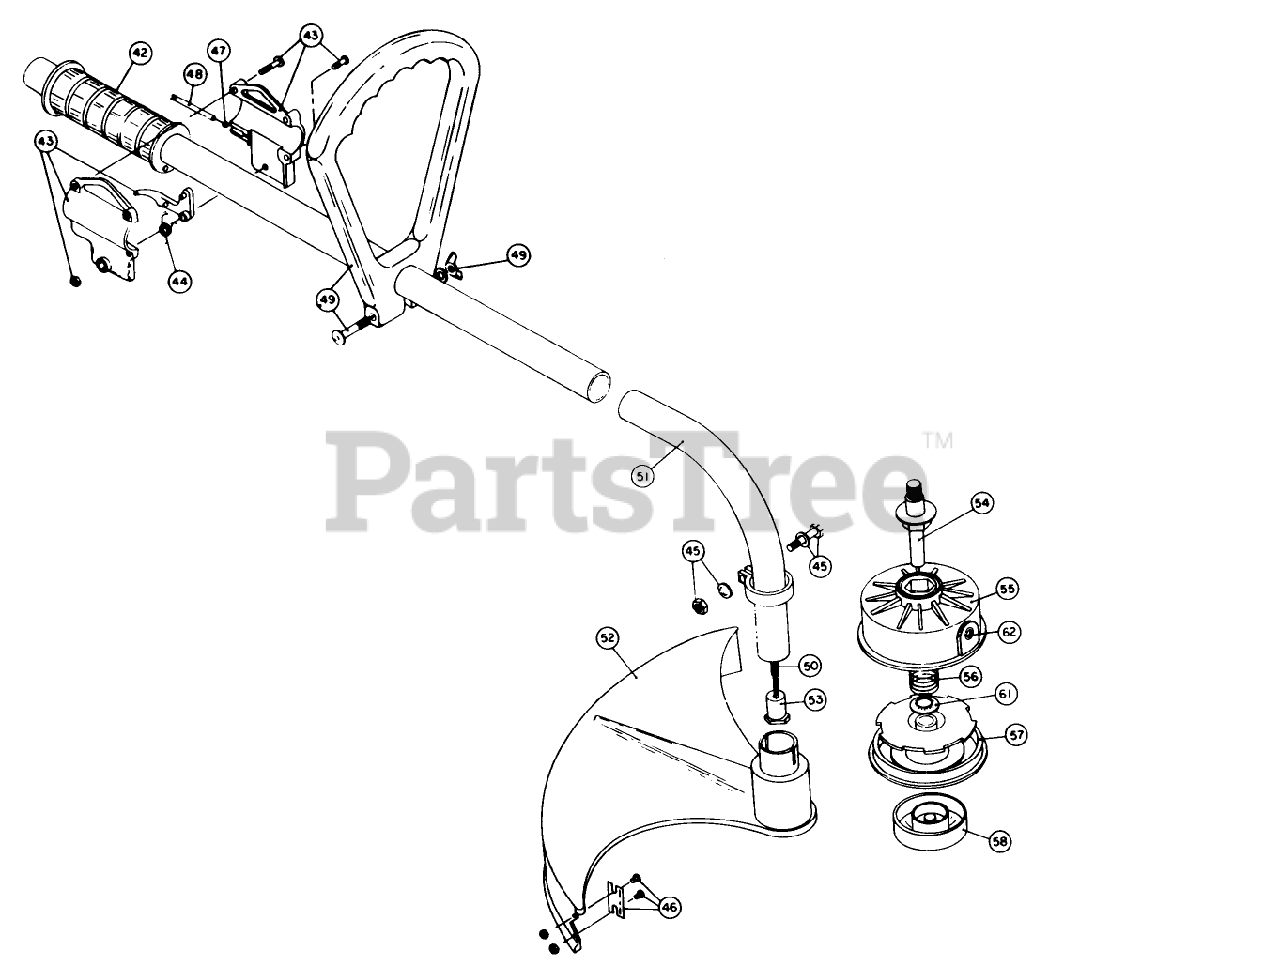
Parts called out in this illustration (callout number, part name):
44	THROTTLE TRIGGER SPRING
46	BLADE ASM
47	THROTTLE CABLE WIRE
48	THROTTLE CABLE HSG
53	SQUARE DRIVE NUT
57	REEL - INNER
61	RETAINER WASHER
